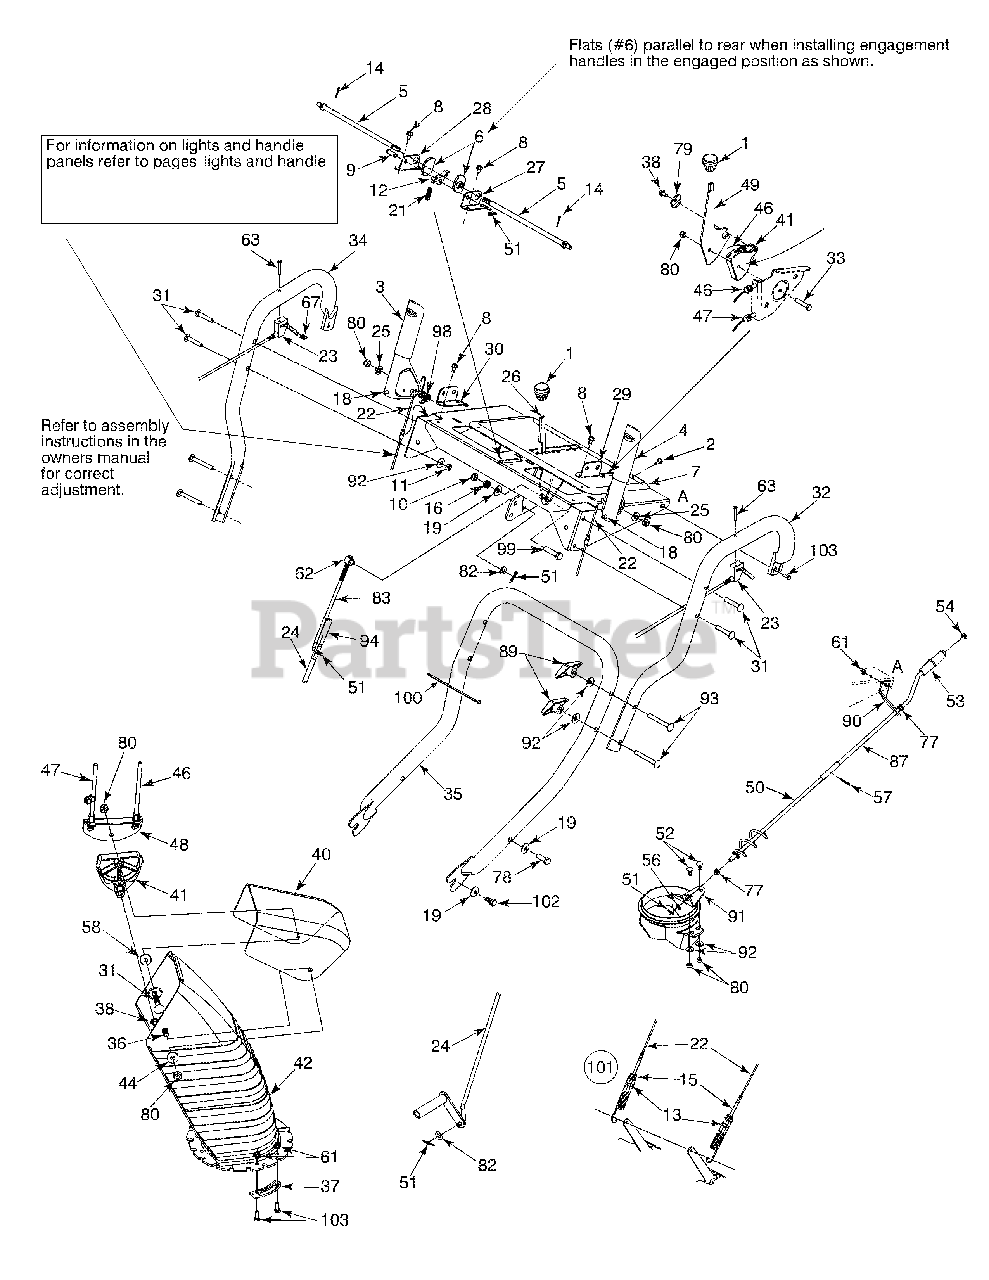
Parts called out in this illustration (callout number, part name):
1	Shift Knob
2	Truss Mach B-Tapp Scr #10-16 x .50 Gr. 5
3	Engagement Handle RH Black
4	Engagement Handle LH Black
6	Cam Handle Lock
9	Clevis Pin .31 Dia. x 1.0" Lg.
10	Hex Nut 3/8-24 Gr. 5
11	Hex Nut 5/16-18 hd. Gr. 5
12	Cam Lock Pawl
13	Hex Ins. Locknut 1/4-20
14	Cotter Pin 3/32 x .75
15	Extension Spring
16	Compression Spring .39 ID x .88 Lg
18	Rubber Bumper
19	Cupped Washer .401 ID x .870 OD x .063
21	Compression Spring .36 DIA x 1.0" LG.
22	Clutch Cable
23	Trigger Assembly
24	Lower Shift Rod
25	Washer (special)
31	Carriage Bolt 5/16-18 x 1.75" Lg.
33	Hex Cap Scr. 5/16 - 18 x 1.50" Lg. Gr. 5
36	Carriage Bolt 5/16-18 x 1.00" Lg
37	Chute Flange Keeper
38	Hex HL Index Washer Screw 1/4-15 X .75
40	Upper Chute Remote Tilt
42	Lower Chute Remote Tilt
44	Flat Washer .349 ID x .879 OD x .063
46	Chute Control Cable 66"
47	Chute Control Cable w/clip
52	Carriage Bolt 5/16-18 x .75 Gr. 2
53	Knob 1.0 x 3.2
54	Push Nut 3/8" Rod
56	Flat Washer .375 ID x .738 OD X.063
57	Internal Cotter Pin
58	Flat Washer .344 ID x 1.125 OD x .125
61	Hex Flg. L-Nut 1/4-20 Gr. F Nylon
62	Adjustment Ferrule
63	Oval C-Sunk Screw #10-24 x 1.75
77	Plastic Bushing .380 ID
78	Hex Screw 3/8-16 x 1.75 Gr.5 w/patch
79	Contour Washer
80	Hex Flg. L-Nut 5/16-18 Gr. F Nylon
81	Hex L-Flanged Nut 1/4-20 Gr. "F"
82	Flat Washer .344 ID x .688 OD x .065
83	Upper Shift Rod
84	Hex Screw 1/4-20 x .75" Lg. Gr. 5
89	Wingnut Knob, 5/16-18
92	Cupped Washer .340 ID x .872 OD x .06
93	Carriage Bolt 5/16-18 x 2.50
94	Connector - Shift Rod
98	Torsion Spring .44 ID
99	Hex Scr 3/8-24 x 1.50 Gr. 5
101	Auger/Drive Cable Assembly
102	Hex Screw 3/8-16 x .880 Gr. 5
103	Hex Screw 1/4-20 x 1.00 Gr. 5
